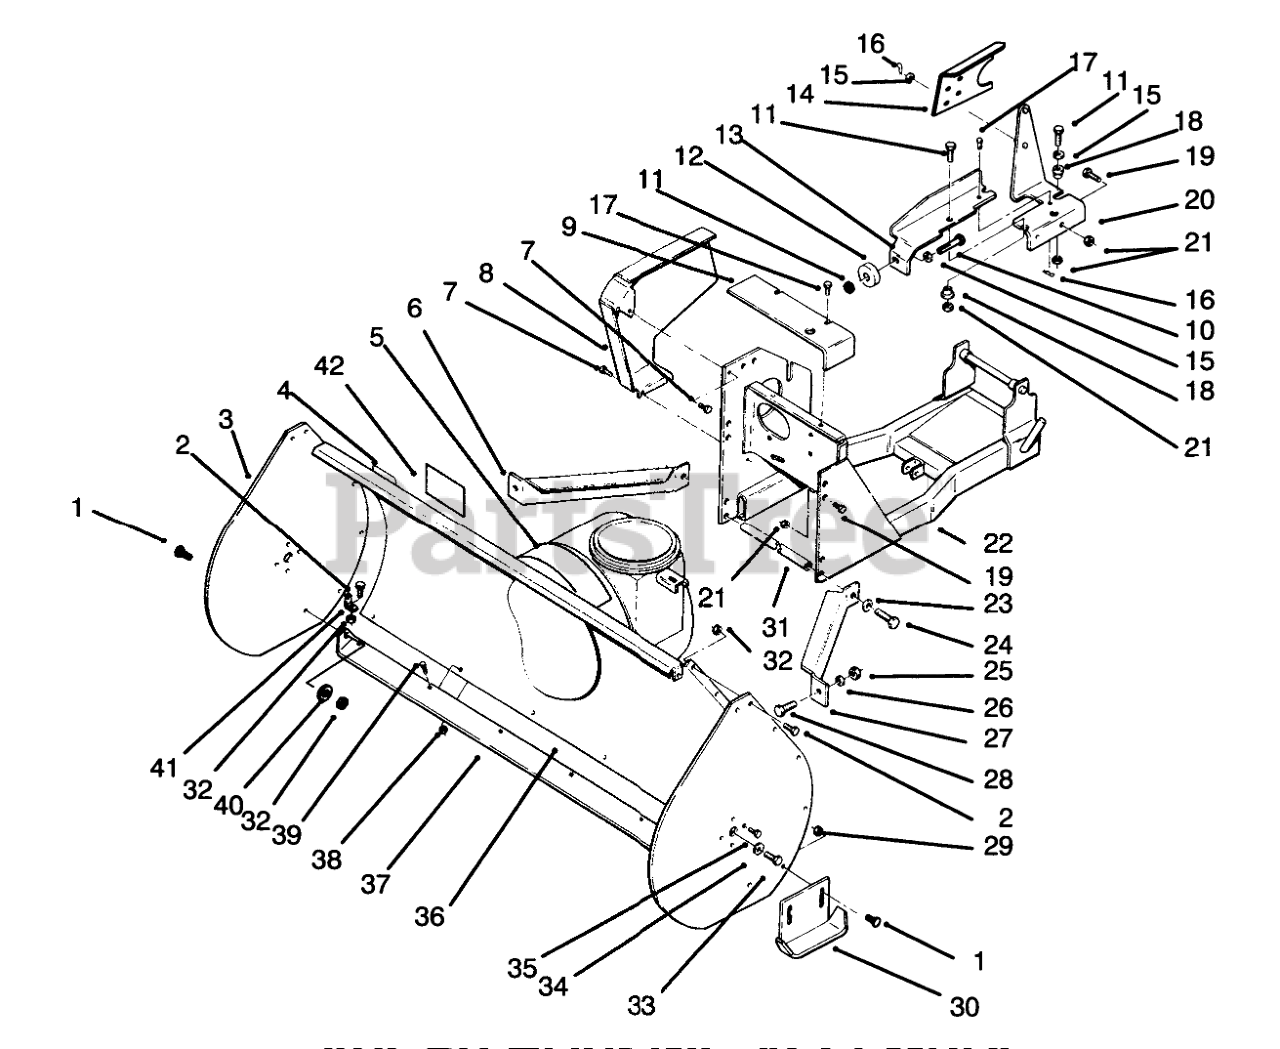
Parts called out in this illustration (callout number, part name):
1	BOLT-CARR
2	SCREW-HH
3	Plate-Side
4	DECAL-DANGER
5	DECAL-ATTACHMENT
6	BRACE-R.H. R
7	SCREW-HWH
8	WLDMT-BELT COVER R
9	GUARD R
10	SCREW
11	SCREW-HH
13	BRACKET-BUMPER R
14	GUARD-BELT R
15	WASHER-FLAT
16	PIN-HAIR
17	CLEVIS PIN
18	SPACER-LIFT LINK
19	SCREW-HH
20	WLDMT-BRKT GUARD R
21	NUT-LOCK, NI
22	WLDMT-CARRIER FRA R
23	WASHER-LOCK
24	SCREW-HH
25	NUT-LOCK, NI
26	WASHER-FLAT
27	BRACE-L.H. R
28	SCREW-CARR
30	Skid
31	BRACE-CROSS R
32	NUT-LOCK, NI
33	SCREW-HH, LOCK
34	WASHER
35	SCREW-HH
36	Housing-Auger (Incl. Ref. #4 & 42)
37	Blade-Scraper
38	NUT-LOCK, NI
39	SCREW-CARR
40	WASHER-PLAIN
41	BLADE SUPPORT BRKT R
42	DECAL-WARNING
